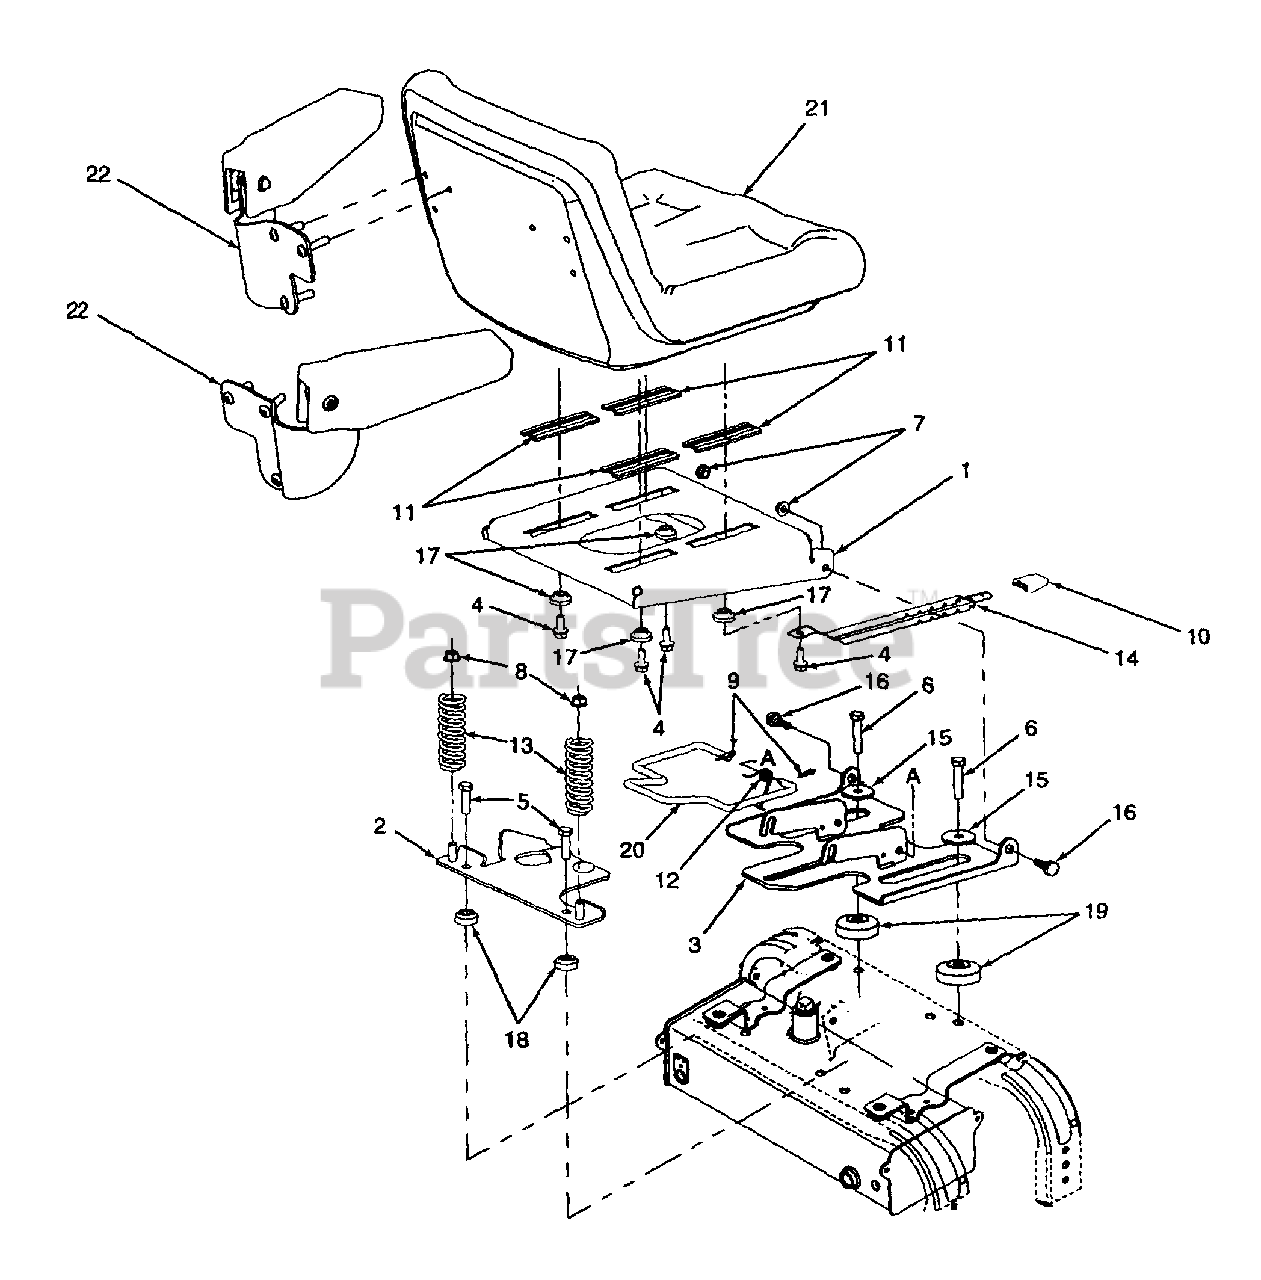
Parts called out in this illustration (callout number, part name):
4	Screw, Hex Wash Hd Tapp 5/16-18 x .75
5	Screw, Hex Cap 3/8-16 x 1.5 GR5
6	Screw, Hex Cap 3/8-16 x 1-3/4 GR5
7	Nut, Hex Flange Lock 5/16-18 GR5
8	Nut, Hex Flange Lock 3/8-16 GR5
9	Pin, Internal Cotter
10	Knob, Seat Adjustment
12	Spring, Torsion
13	Spring, Compression
14	Spring, Index
15	Washer, Flat, .390 x 1.5 x .134
16	Bolt, Shoulder .437 x .268:5/16-18
17	Spacer, Shoulder, .38 I.D.
18	Spacer, Shoulder
19	Spacer, Seat Pan Shoulder
20	Rod, Seat Pan Lock
21	Seat Assembly
22	Seat Arm (Set of Two)
